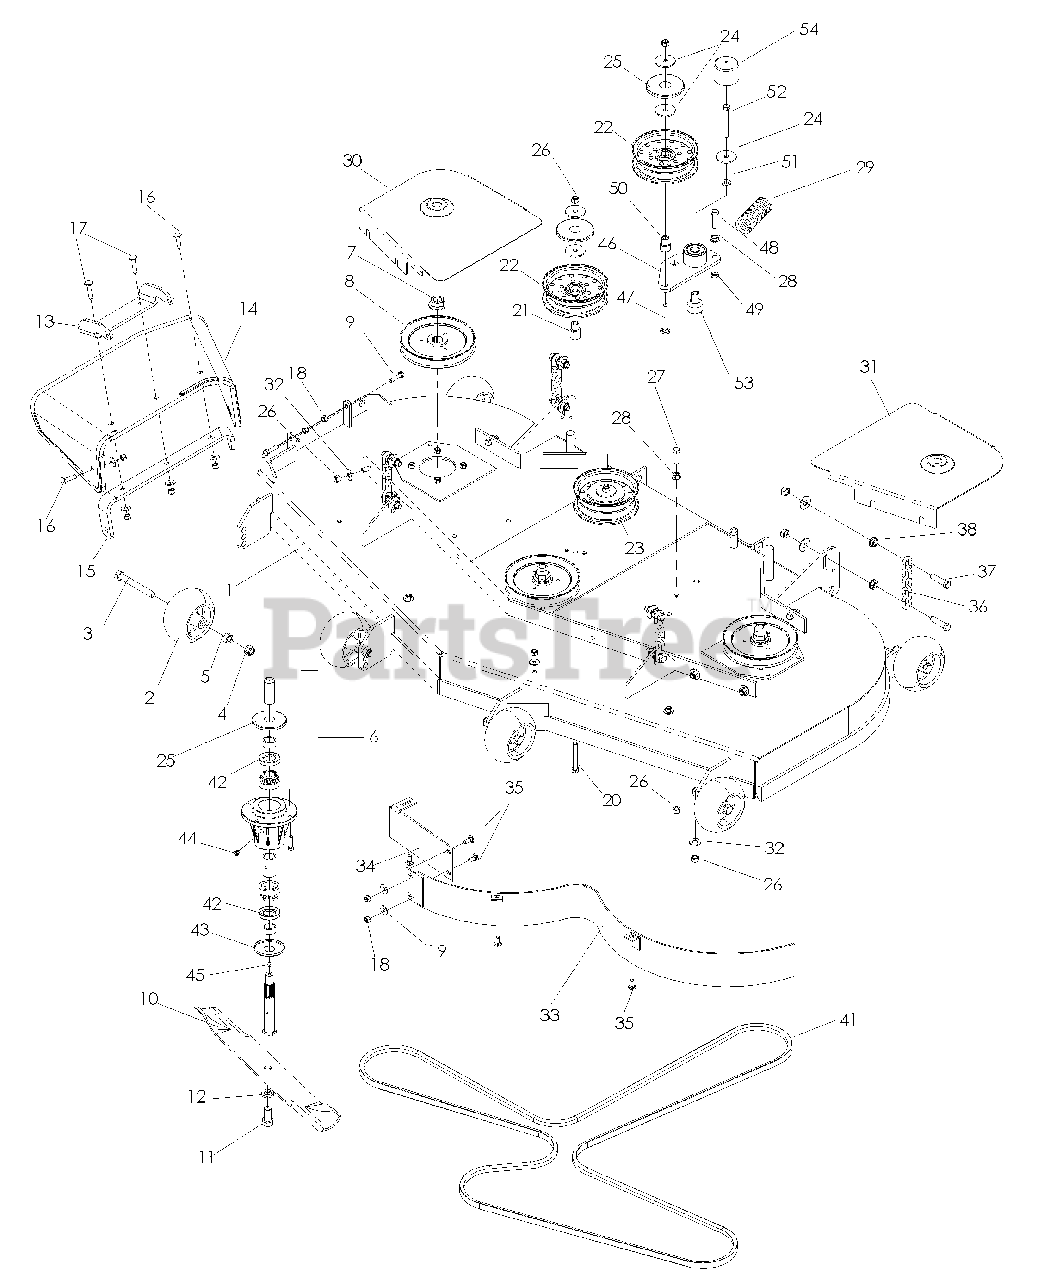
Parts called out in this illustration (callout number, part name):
1	DECK W/DECALS
2	WHEEL, GAUGE
3	HCS 1/2-13 x 4
4	NUT 1/2-13 HEX NYLOC
5	NUT 1/2-13 HEX
6	HOUSING ASSM, 52/61
7	NUT, FLANGE 3/4-16
8	PULLEY, 61
9	HCS 5/16-18 x 1 1/4
10	BLADE, 21"
11	HCS 5/8-18 x 1 1/4
12	WASHER 5/8 SLW
13	PIVOT BRACKET, CHUTE
14	RUBBER CHUTE, 52/61
15	BRACKET, REINFORCE
16	RHSNB 5/16-18 x 1 1/4
17	RHSNB 5/16-18 x 1 1/2
18	NUT 5/16-18 HEX NYLOC
19	WASHER 5/16 STD FLT
20	HCS 3/8-16 x 2 3/4
21	BUSHING, IDLER
22	IDLER PULLEY
23	IDLER PULLEY
24	WASHER 3/8 SPECIAL
25	TOP DUST CAP
26	NUT 3/8-16 HEX NYLOC
27	HCS 3/8-16 x 1 1/4
28	NUT 3/8-16 HEX WHIZLK
30	61 BELTSHIELD RT
31	61 BELTSHIELD LT
32	WASHER 3/8 STD FLT
33	BAFFLE MAIN
34	BAFFLE CENTER
35	RHSNB 5/16-18 x 3/4
36	LIFT CHAIN
37	HCS 7/16-14 x 1 3/4
38	NUT 7/16-14 HEX WHIZ LK
39	WASHER 7/16 FLAT
40	NUT 7/16-14 HEX NYLOC
41	BELT, DECK 61"
42	SHAFT SEAL
43	BOTTOM DUST CAP
44	GREASE POPPET
46	ARM, IDLER - W/BEARINGS
47	RHSNB 3/8-16 x 2 3/4
48	HCS 3/8-16 x 1 1/2 GR 8
49	NUT 3/8-16 HEX JAM
50	BUSHING, IDLER
51	WASHER 3/8 SAE FLT
52	HCS 3/8-16 x 3
53	PIVOT, BEARING
54	CAP, VINYL
